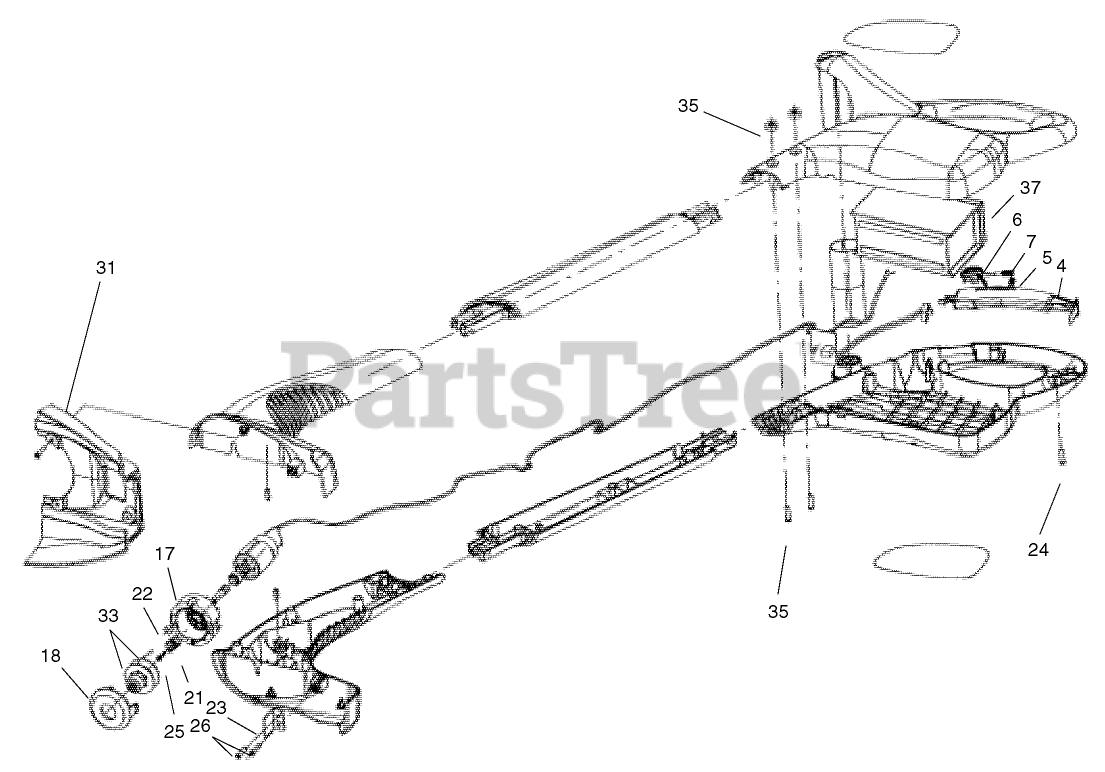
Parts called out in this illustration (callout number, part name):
4	TRIGGER
5	SPRING-TRIGGER, 7IN
6	LOCK-TRIGGER
7	SPRING-COMPRESSION, TRIGGER
17	DRUM-TRIMMER, 7IN
18	CAP-SPOOL, 7 INCH
21	SPRING-COMPRESSION
22	EYELET
23	CUTTER
24	SCREW-PLASTIC THD FORM
25	SCREW-MACHINE
26	SCREW-PLASTIC THREAD FORM
31	SHIELD-7IN TRIMMER (CE)
33	SPOOL ASM
35	ASM-BOLT BAG
37	7IN BATTERY ASM - WET
